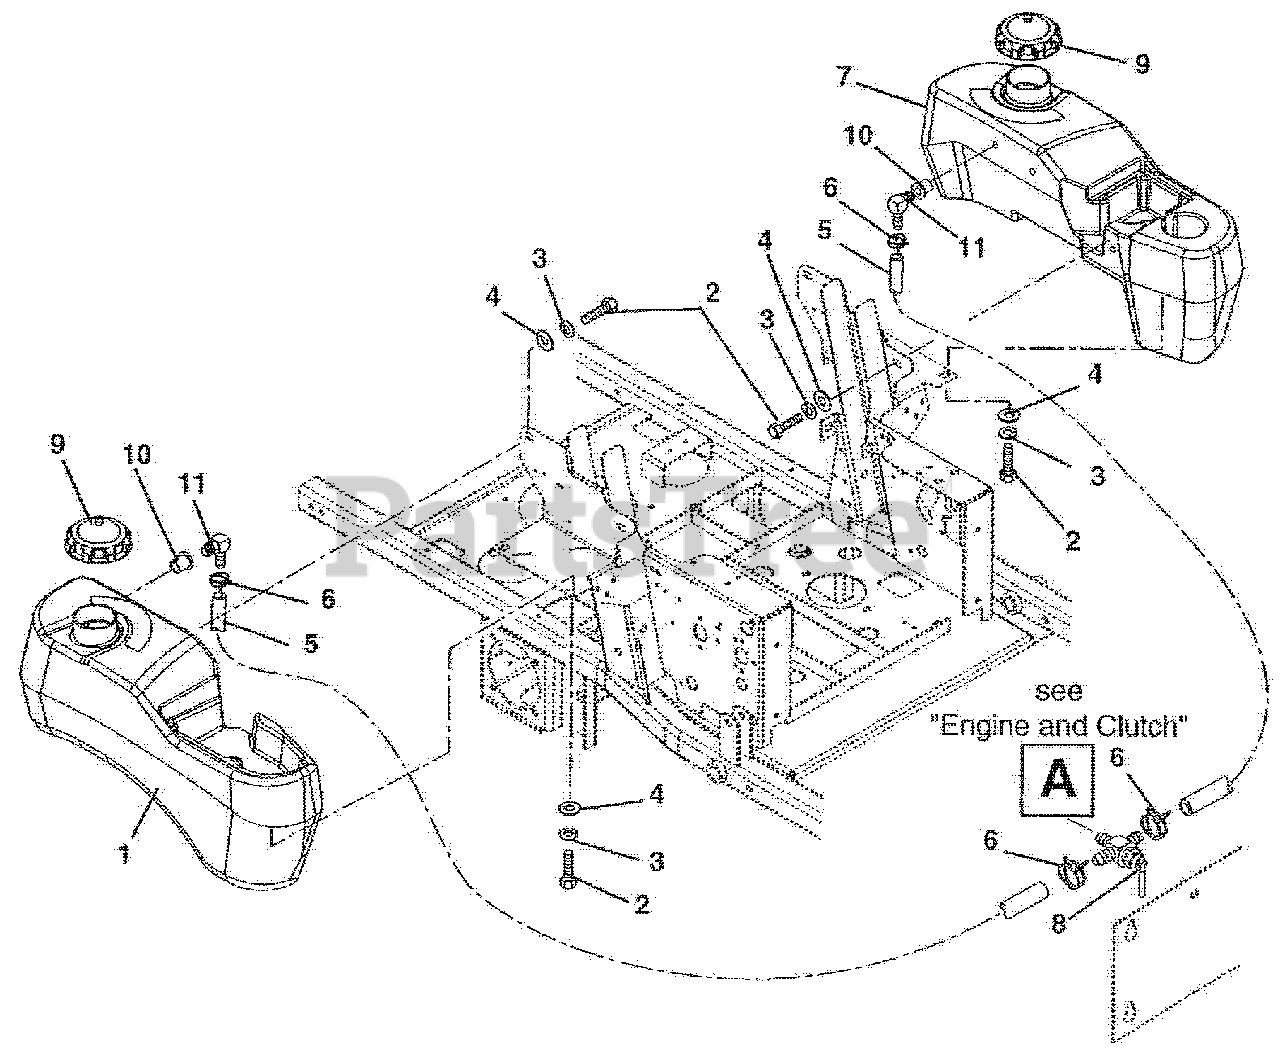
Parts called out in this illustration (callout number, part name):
1	Tank, Fuel - Right Hand
2	Bolt, Hex .31-18 x .75 Grade 5
3	Washer, Locking .31 x .078
4	Washer, Flat Steel .38 x .875 x .083
5	Gas Line, Bulk .25 I.D. (2 @ 63in)
6	Clamp, Hose Wire .49/.51 x .116
7	Tank, Left Hand Fuel (EYE-Q)-200 Series
8	Valve, Fuel
9	Cap, Gas
11	Tank Fitting
